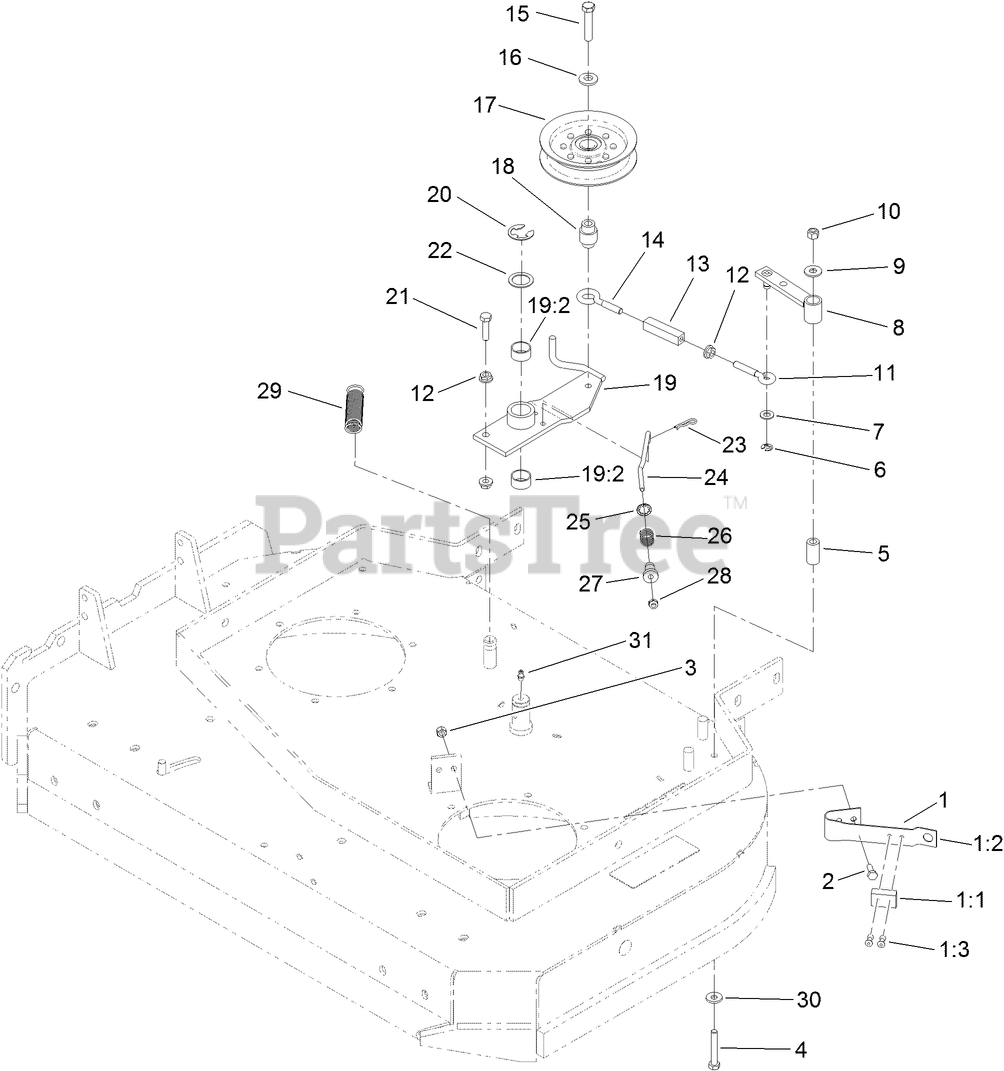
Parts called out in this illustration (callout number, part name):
1	PAD AND SPRING ASM
1:1	PAD-BRAKE
1:2	SPRING
1:3	RIVET-POP
2	SCREW-HH
3	NUT-LOCK, NI
4	SCREW-HH
5	TUBE-PIVOT
6	RING-RETAINING, EXT
7	WASHER-PLAIN
8	ARM-ASSIST, 32/36
9	WASHER-FLAT
10	NUT-LOCK, NI
11	EYEBOLT-THREAD, RH
12	NUT-HF
13	BODY-TURNBUCKLE
14	EYEBOLT-THREAD, LH
15	SCREW-HH
16	WASHER-BELLEVILLE
18	BUSHING-ENGAGEMENT
19	IDLER ARM ASM
19:2	SLEEVE-BEARING
20	RING-RETAINING, EXT
21	SCREW-HH, SPECIAL
22	WASHER-SPINDLE
23	PIN-COTTER
24	ROD-BRAKE
25	RING-PUSH ON
26	SPRING-COMPRESSION
27	SPACER-FLANGED
28	NUT-LOCK, NI
29	SPRING-EXTENSION
30	WASHER-SPRING
31	FITTING-GREASE, 90 DEG
